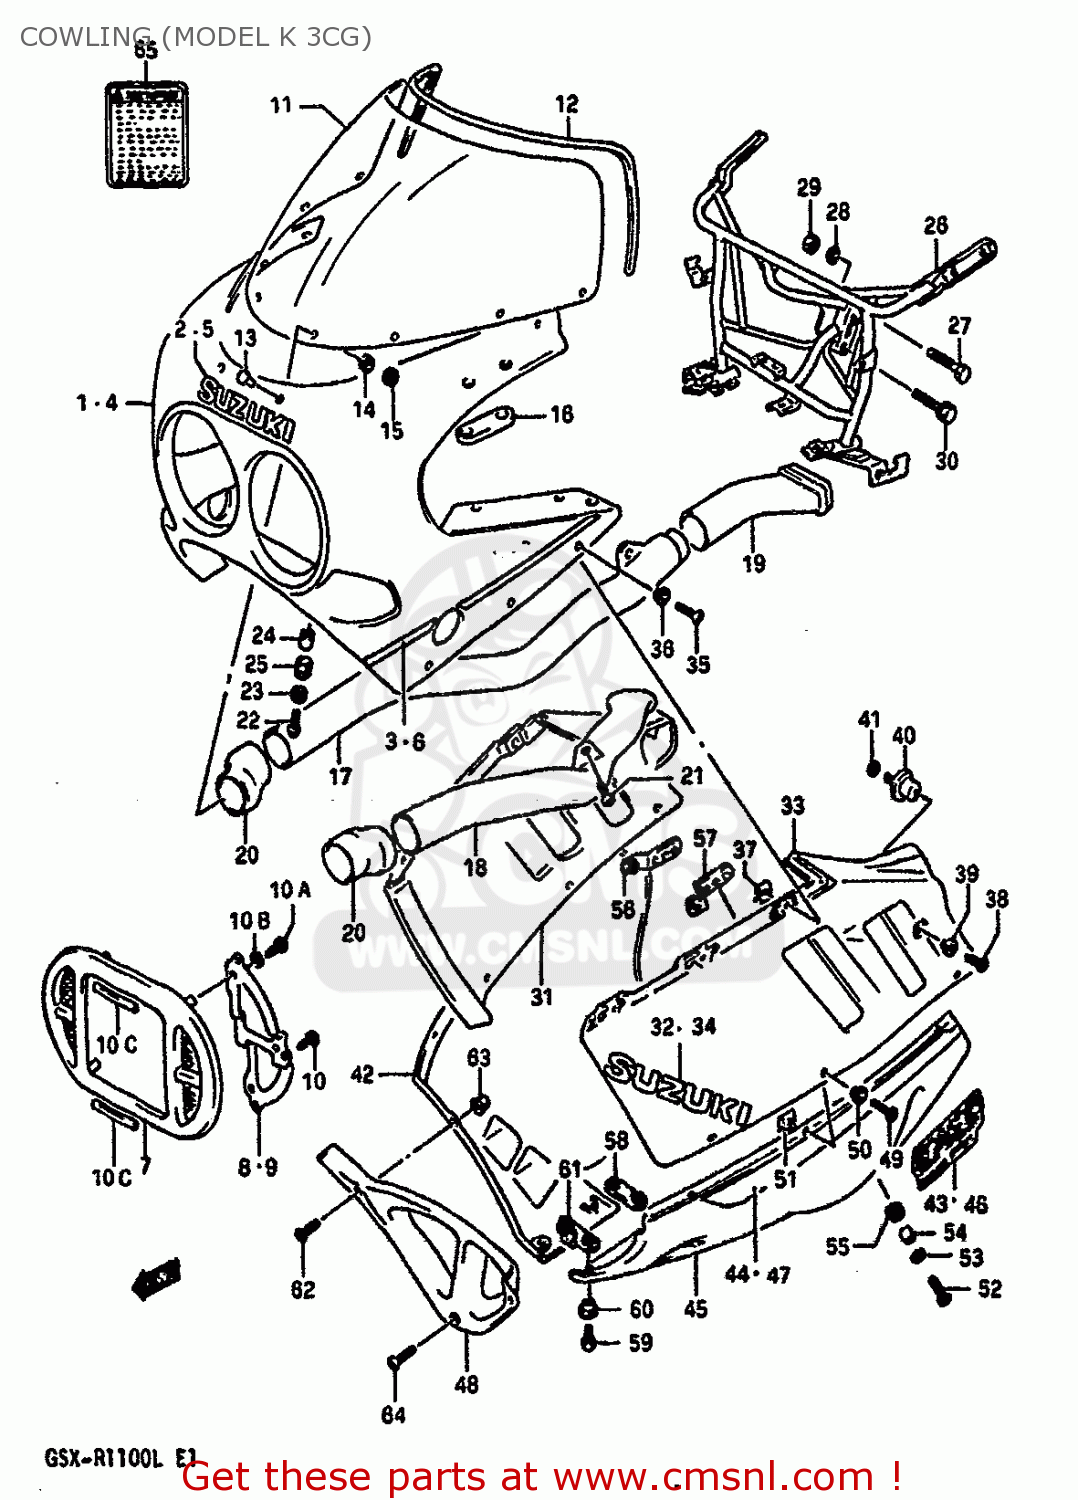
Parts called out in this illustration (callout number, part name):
1	BODY ASSY,COWLING
2	EMBLEM,COWLING FR
3	TAPE SET,COWLING
4	BODY ASSY,COWLING (BLACK/GRAY)
5	EMBLEM,COWLING FR
6	TAPE SET,COWLING
7	COVER,FRONT (BLACK)
8	PLATE,COVER RH
9	PLATE,COVER LH
10	TAPPING SCREW 4X10/A
10A	SCREW
10B	SPACER
10C	CUSHION
11	SCREEN SET,WIND
12	MOLDING
13	PIN,WINDSCREEN
14	CUSHION
15	NUT
16	CUSHION,RR VIEW MIRRORR
17	PIPE,AIR INTAKE FR,R
18	PIPE,AIR INTAKE,FRONT
19	PIPE,AIR INTAKE RR,R
20	JOINT,AIR INTAKE
21	SCREW, CENTER
22	SCREW(6X20)
23	WASHER(6.5X18X1)
24	SPACER
25	CUSHION
26	BRACE,COWLING
27	BOLT
28	WASHER,LOCK,8.
29	NUT ,8MM
30	BOLT
31	COVER,COWLING SIDE,R
32	EMBLEM,COWLING SIDE
33	COVER,COWLING SIDE,L
34	EMBLEM,COWLING SIDE
35	SCREW(5X18)
36	WASHER(5.2X14X1.5)
37	NUT,HEADLAMP HOUSING,UPPER
38	SCREW(6X12)
39	WASHER(6.3X16X1.5)
40	CUSHION,COWLING
41	WASHER,LOCK
42	COVER,COWLING
43	EMBLEM
44	TAPE,COWLING,UNDER,RIGHT
45	COVER,COWL LH
46	EMBLEM
47	TAPE,COWLING,UNDER,LEFT
48	COWLING,UNDER,CENTER
49	SCREW(5X18)
50	WASHER(5.2X14X1.5)
51	NUT,HEADLAMP HOUSING,UPPER
52	SCREW(6X20)
53	WASHER(6.5X18X1)
54	SPACER
55	CUSHION
56	BRACKET
57	BRACE,COWLING UNDER,LH
58	BRACE,COWLING LWR COVER RR
59	SCREW(6X16)
60	WASHER(6.3X16X1.5)
61	BRACE,COWLING LWR COVER
62	SCREW(5X14)
63	NUT
64	SCREW(6X16)
65	LABEL (WARNING)
